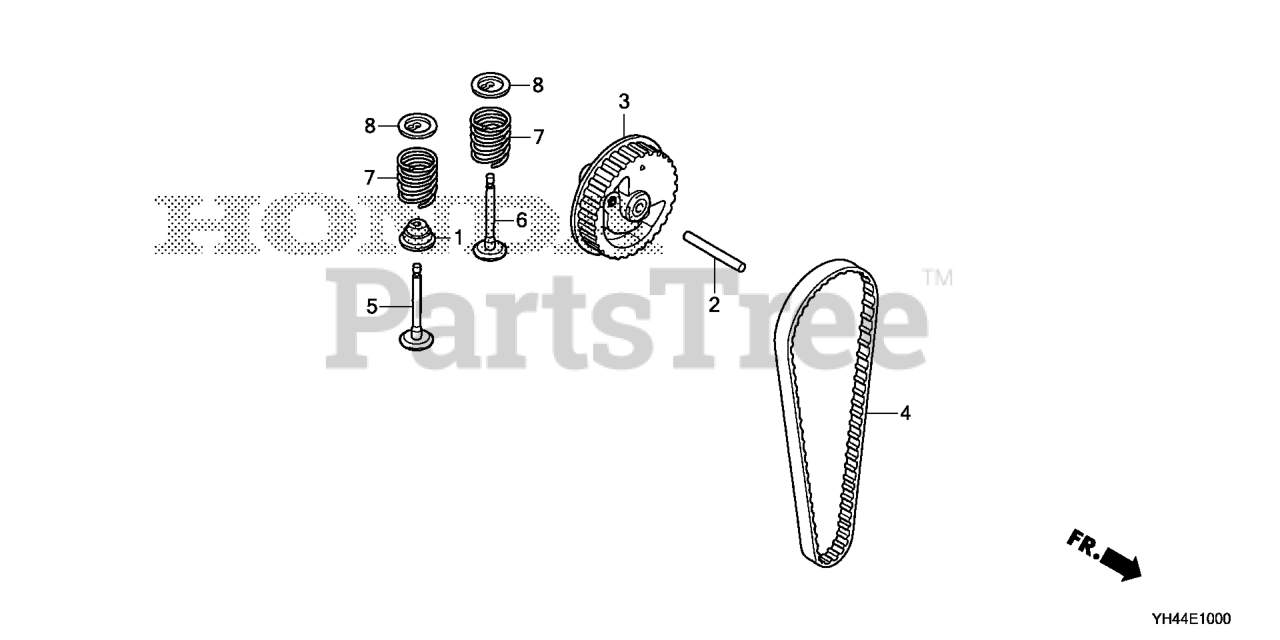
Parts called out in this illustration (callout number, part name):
1	SEAL, VALVE STEM
2	ROLLER (4X29.8)
3	PULLEY, CAMSHAFT
4	BELT, TIMING (71ZU5 G-310)
5	VALVE, IN. (EI)
6	VALVE, EX. (EE)
7	SPRING, VALVE
8	RETAINER, VALVE SPRING
